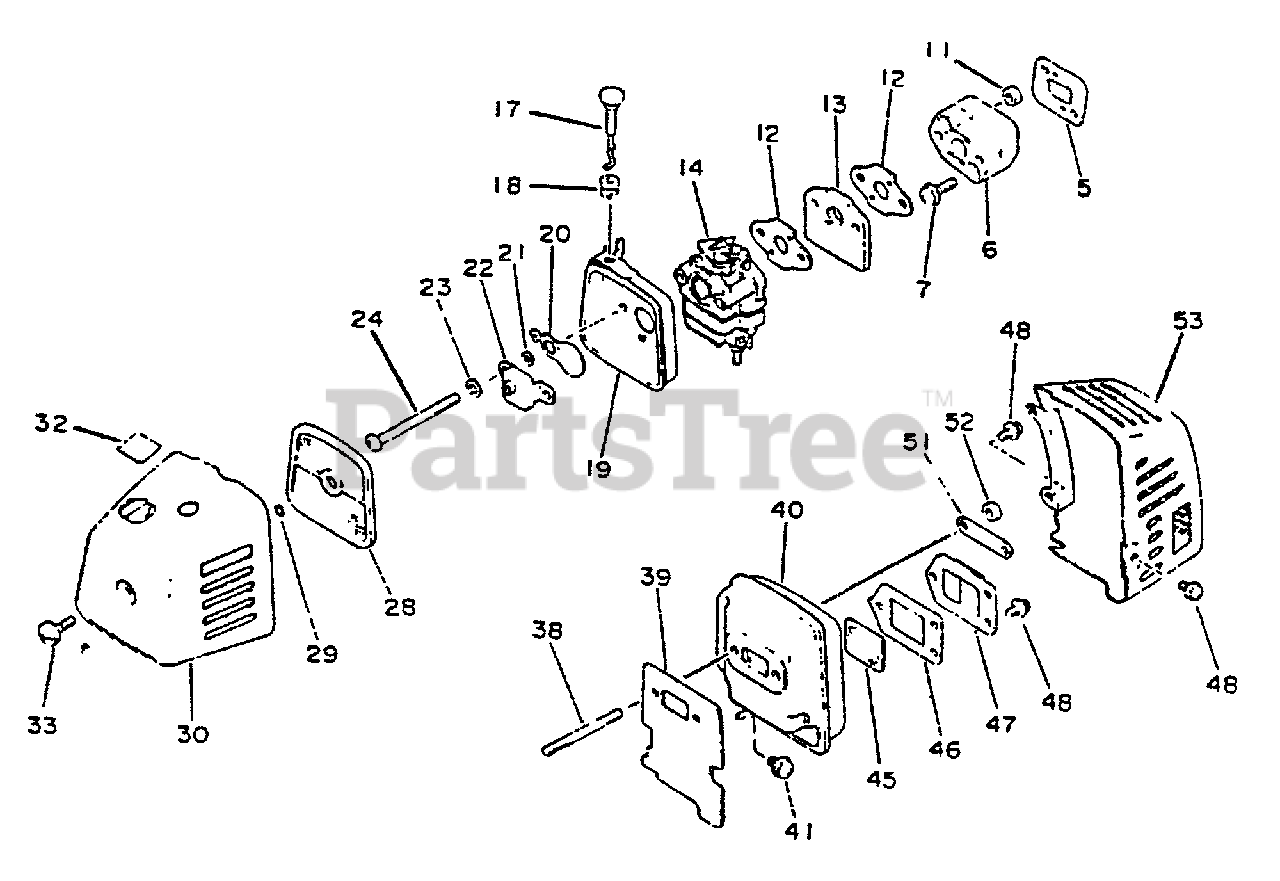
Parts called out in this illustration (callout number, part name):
5	GASKET, INTAKE
6	INSULATOR, INTAKE
7	SCREW - 5X20
12	GASKET, INTAKE
13	INSULATOR
14	CARBURETOR WY-18
17	ROD, CHOKE
19	CASE, AIR FILTER
20	SHUTTER, CHOKE
21	WASHER - 5
22	PLATE, PREVENT
23	LOCKWASHER - 5
24	SCREW - 5X60
28	FILTER, AIR
29	O-RING - 4
30	AIR FILTER COVER ASSY
32	LABEL - CHOKE
39	GASKET, EXHAUST
41	SCREW - 5X10
45	SCREEN, SPARK ARRESTOR
46	SCREEN, SPARK ARRESTOR
47	GUIDE, EXHAUST
48	SCREW - 4X10
52	LOCKNUT - 5
53	COVER, EXHAUST
